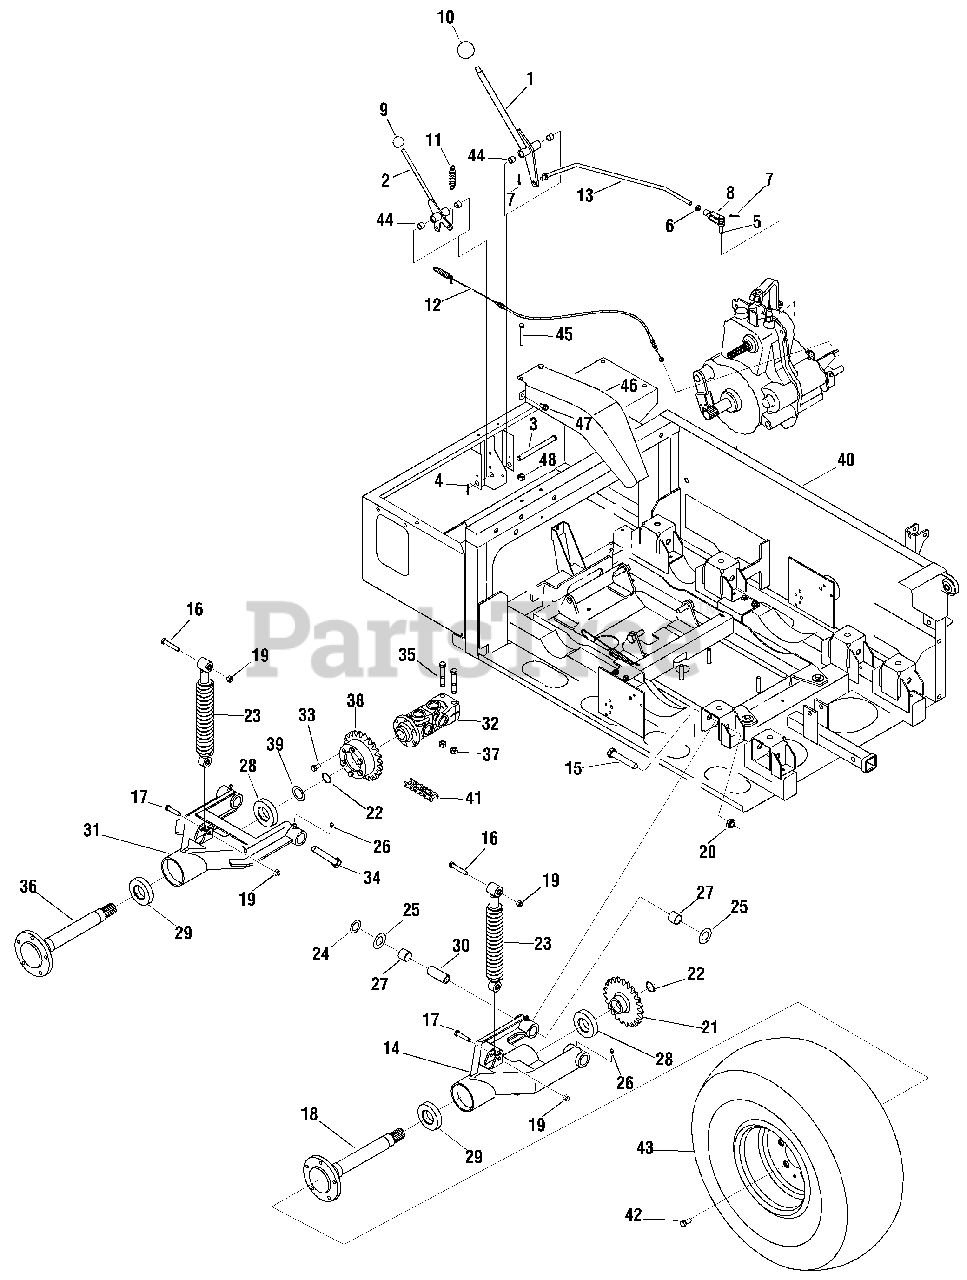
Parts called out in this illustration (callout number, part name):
1	Lever Assembly, Transmission
2	Shifter Assembly, Differential Lock
3	Pin, Clevis, .50 x 5.375
4	Pin, Cotter
5	Pin, Clevis, .375 x 2.0
6	Nut, Jam, 3/8-24
7	Pin, Cotter, .072 x 1.13
8	Clevis, Adjustment
9	Knob, Ball
10	Knob, Ball
11	Spring, Extension, .637 x 2.972
12	Control Cable, Differential Lock
13	Shifter Rod, Transmission
16	Screw, 3/8-16 x 2.25
17	Screw, 3/8-16 x 1.75
18	Axle Shaft, Rear Drive
19	Nut, Hex Lock, 3/8-16
20	Jam Nut, Lock, 5/8-18
22	Retaining Ring, External, 1.14
23	Shock Absorber, 2.9Stroke
24	Washer, Flat, 1.06 x 1.56 x .020
25	Washer, Flat, 1.010 x 1.86 x .060
26	Lube Fitting, 3/16
27	Bearing Flange, 1.0 x 1.125 x 1.0
28	Ball Bearing, Internal Axle
29	Ball Bearing, External Axle
30	Spacer, .63 x 1.0 x 2.594
32	Weld Coupling Assembly
33	Screw, Hex, 3/8-16 x .75, Gr5
34	Screw, Hex, 5/8-18 x 3.5, Gr5
35	Screw, Hex, 7/16-14 x 2.75, Gr5
36	Axle Shaft, Drive Center
37	Nut, Hex Lock,7/16-14
38	Sprocket, Hub, 1.75 - 23T
39	Spacer, 1.78 x 1.88
40	Frame Assembly, Complete
41	Chain, 60-97 Pitch
42	Hex Screw, 7/16-20 x 1.5, Gr5
43	Wheel Ass'y, 25 x 11 x 10, RH, All Terr.
44	Bushing, .504 x .628 x .50
45	Hex Screw, 5/16-18 x 2.50
46	Belt Guard
47	Screw, 5/16-18 x .625
48	Hex Lock Nut, 5/16-18
